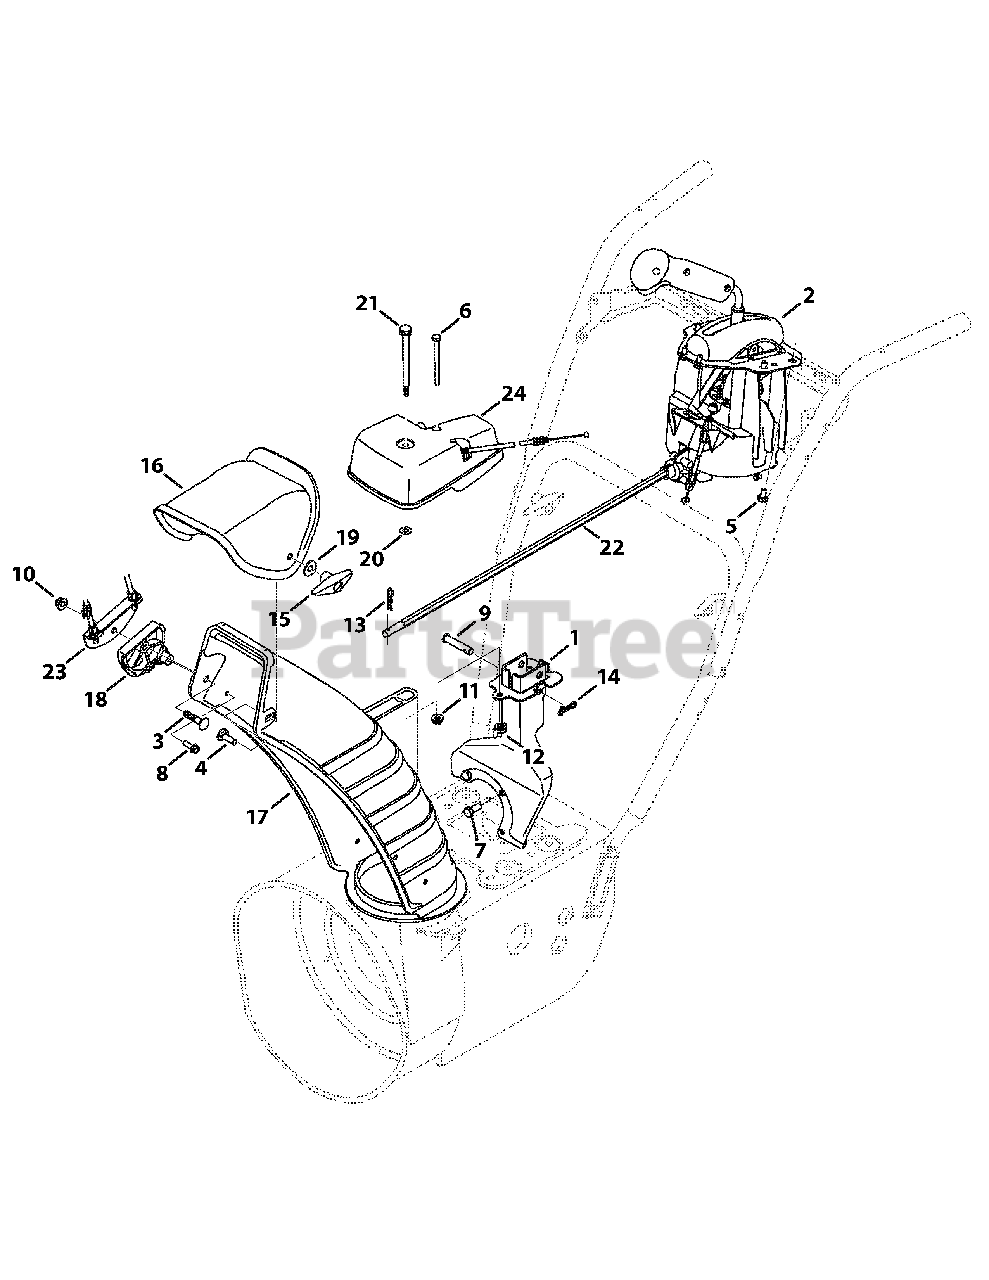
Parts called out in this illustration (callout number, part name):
1	Chute Support Bracket
2	Complete Control Assy
3	Bolt, Carriage, 5/16-18 x 1.50
4	Bolt, Carrier, 5/16-18 x 1.00
5	Screw, HL, 1/4-15 x 0.50
6	Hex Head Screw, 1/4-20 x 3.00
7	Hex Head Screw, 5/16-24 x .750
8	Screw, HL, 1/4-15 x 0.750
9	Clevis Pin, 3/8 x 1.87
10	Nut, Flangelock, 5/16-18
11	Nut, Flangelock, 1/4-20
12	Wing Nut, 1/4-20
13	Internal Cotter Pin
14	Bow-Tie Cotter Pin
15	Star Knob, 5/16-18
16	Chute, Upper
17	Chute, Lower
18	Cable Guide, Chute Tilt
19	Washer, Flat, .349 x .879 x .063
20	Washer, Flat, .25 x .630 x .0515
21	Screw, Shoulder, .312 x 3.5 x 1/4-20
22	Chute Rod, 3/8 Hex
23	Cable Bracket
24	Gearbox Assembly, Chute Rotation
